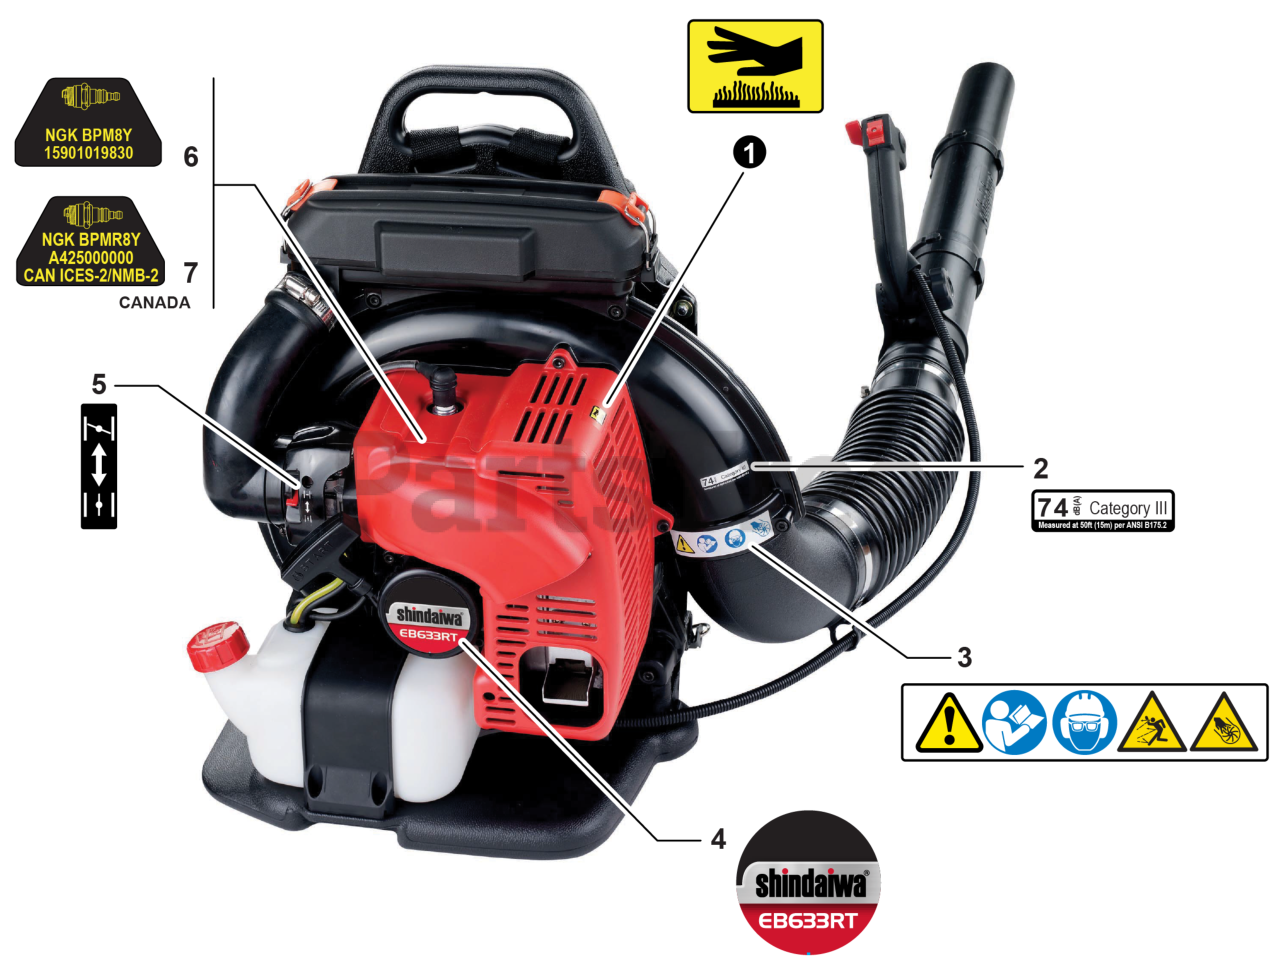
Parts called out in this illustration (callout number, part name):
1	LABEL - CAUTION - HOT
2	LABEL - NOISE - 74DB(A) CAT. III
3	LABEL - CAUTION - ISO
4	LABEL - MODEL - EB633RT
5	LABEL - CHOKE
6	LABEL - SPARK PLUG - BPM8Y
7	LABEL - SPARK PLUG - BPMR8Y
